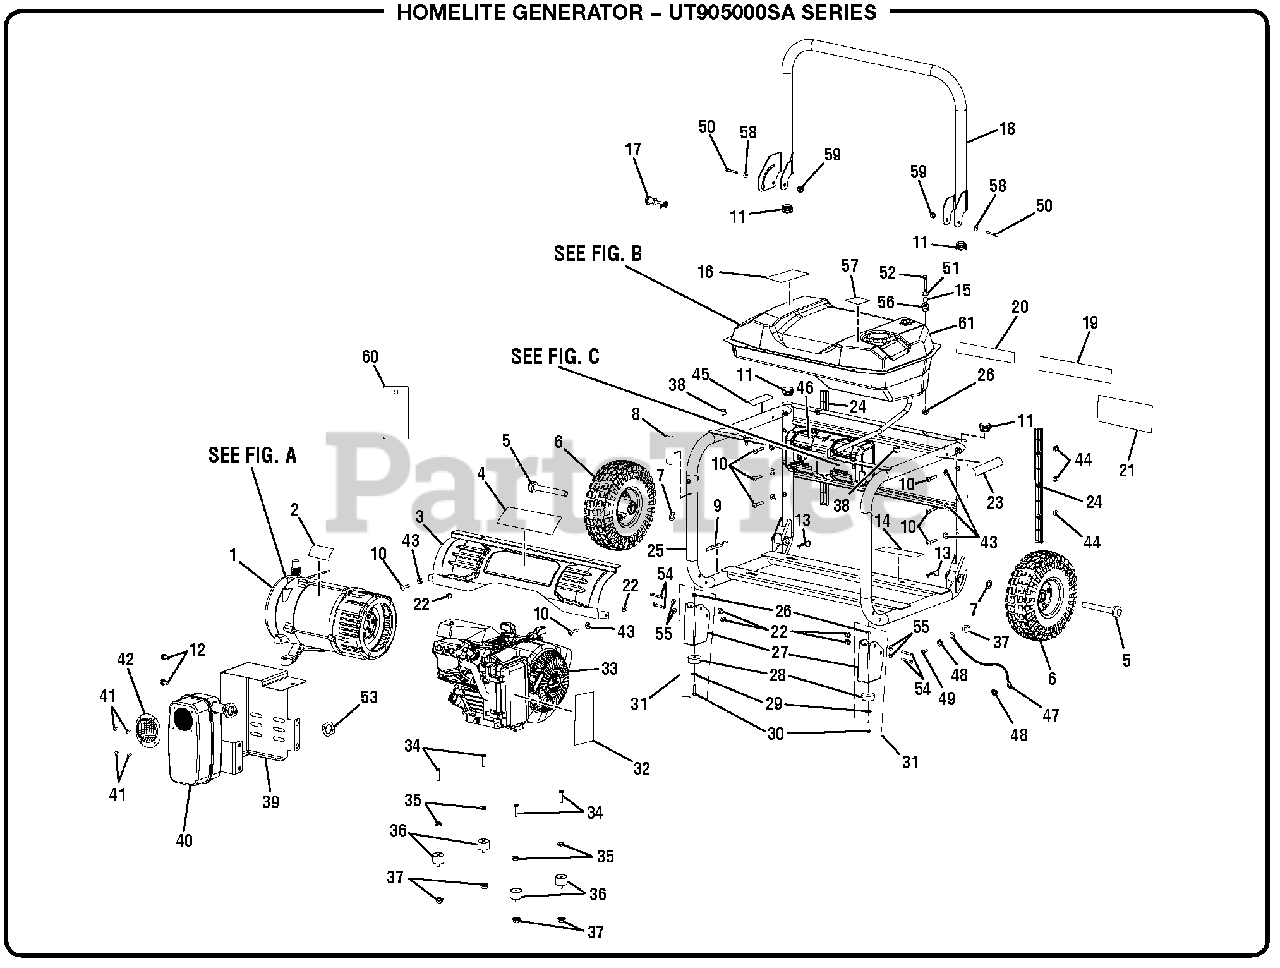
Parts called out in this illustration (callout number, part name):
1	Generator Head Assembly (See Figure A)
2	Data Label
3	Back Panel Assembly
4	Back Panel Logo Label
7	Washer (5/8 in)
8	Hot Surface Label
9	Label (UL fire warning)
10	Bolt (1/4-20 x 425 mm, Torx Hd)
12	Bolt (5/16-24 x 5/8 in)
13	Hitch Pin
14	Lubricant Label
15	Spacer (Fuel Tank Isolator)
16	CPSC Label
17	Handle Release Pin Assembly
18	Handle Assembly
19	Danger Label
20	Ground Warning Label
21	Logo Label
22	Lock Nut (1/4-20)
23	Fire Danger Label
24	Frame Slide Rails
25	Frame Assembly
26	Lock Nut (1/4-20)
29	Washer (1/4 in)
30	Bolt (1/4-20 x 1 in, Hex Hd)
31	Foot Assembly
32	Starting Instruction Label
34	Bolt (5/16-18 x 15 in)
35	Lock Washer (5/16)
36	Isolator (Generator)
37	Hex Nut (5/16-18, Flange)
38	Rubber Handle Bumper
39	Back Muffler Cover
40	Muffler (Subaru EX30)
41	Screw (8-32 x 3/8 in)
42	Spark Arrestor
43	Lock Washer (M6)
44	Hex Nut (1/4-20)
45	Pin Release Label
46	Control Panel (See Figure C)
47	Ground Wire Assembly
48	Star Washer (5/16 in)
49	Bolt (5/16-18 x 3/4 in)
50	Bolt (M8 x 55 mm, Hex Hd)
51	Washer (1/4 in)
52	Bolt (1/4-20 x 1 in)
53	Muffler Gasket
54	Bolt (1/4-20 x 2 in, T30 Torx Hd)
55	Washer (1/4 in)
56	Isolator (Fuel Tank)
57	E85 Label
58	Washer (3/8 in)
59	Hex Nut (M8)
60	Danger Hang Tag
61	Fuel Tank Assembly
